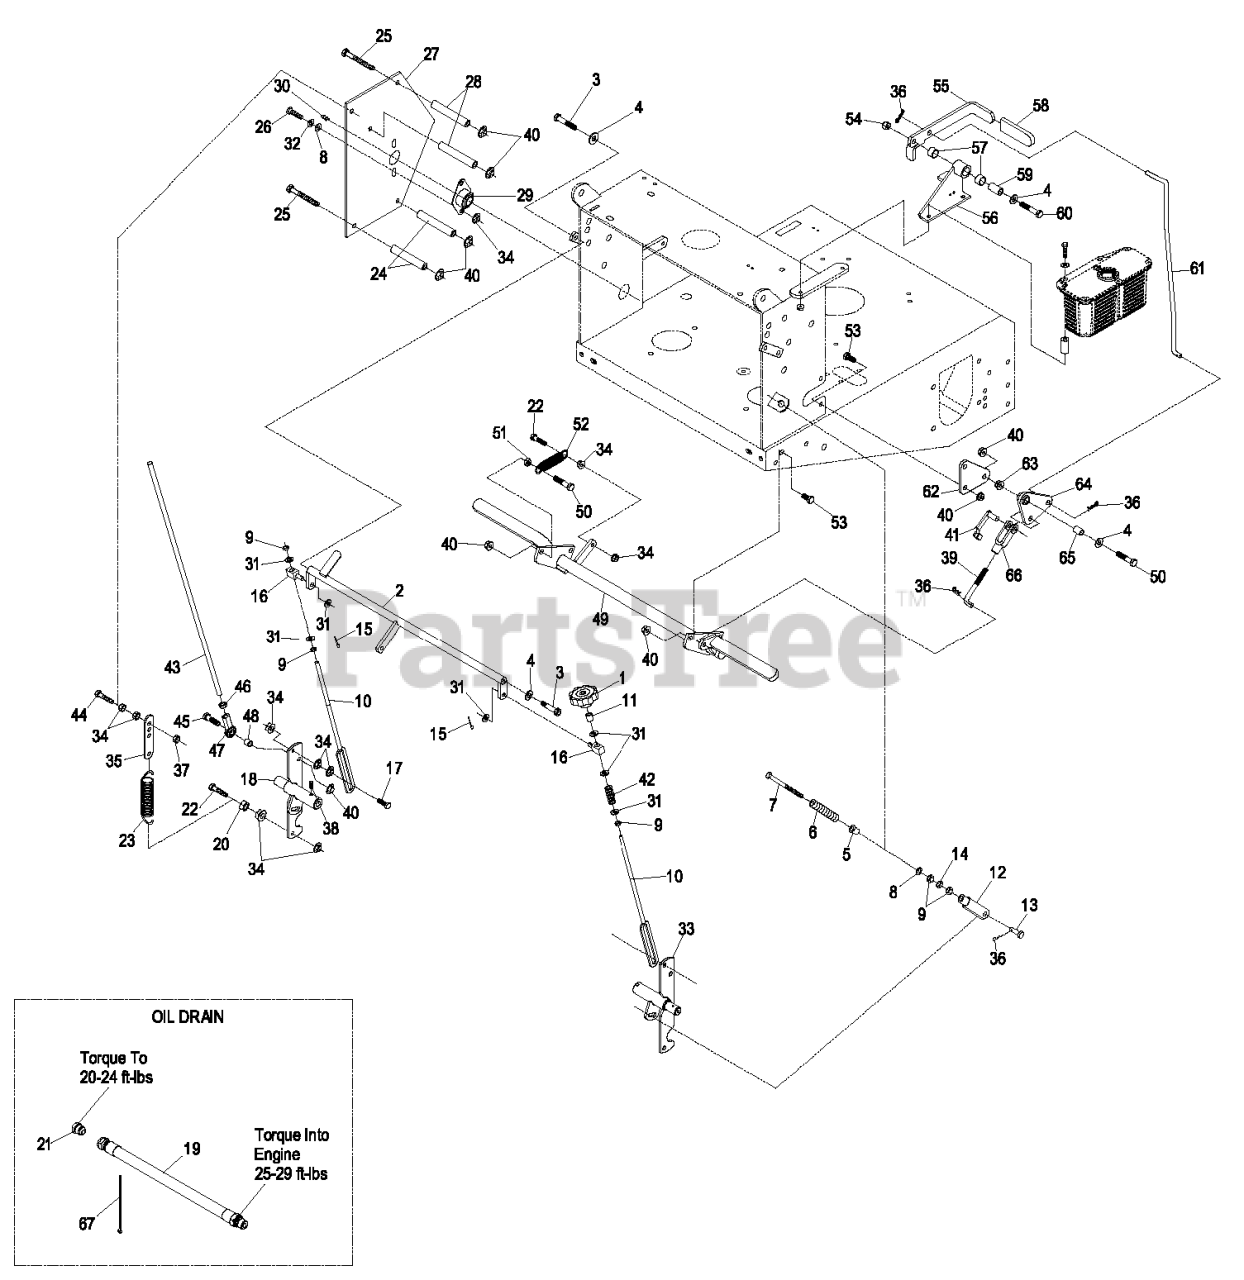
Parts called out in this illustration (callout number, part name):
1	KNOB-TRACKING
2	CRANK-CONTROL, SPEED
3	SCREW-HSH
4	WASHER-FLAT
5	BUSHING-FLANGED
6	SPRING,COMPRESSION (NEUT)
7	BOLT-RETURN, NEUTRAL
8	WASHER-FLAT
9	NUT-HEX
10	LINK-CONTROL, SPEED
12	YOKE-ADJUSTABLE
13	PIN-CLEVIS
14	NUT-JAM
15	PIN-COTTER
17	SCREW-HH
18	SHAFT-CONTROL, LH
20	NUT-JAM
22	SCREW-HH
23	SPRING-EXTENSION
24	SPACER-SHIELD
25	SCREW-HH
26	SCREW-HH
27	SHIELD-CONTROL
28	SPACER-SHIELD
29	BEARING-FLANGE, SIDE
30	FITTING-GREASE
31	WASHER-PLAIN
32	WASHER-LOCK
33	SHAFT-CONTROL, RH
35	TAB-SPRING, EXTENSION
36	PIN-COTTER
37	NUT-LOCK, NI
38	SCREW-SET
39	LINKAGE-LOWER
40	NUT-HHF, WHIZ
41	PIN-SPRING, CLEVIS
42	SPRING-COMPRESSION
43	LINKAGE,DRIVE (PLT)
44	BOLT-TAP, HH
45	SCREW-HH
46	NUT-HEX JAM, LH
47	JOINT-BALL END, LH
48	SPACER-TUBE, PUMP LINK
50	SCREW-HH
51	NUT-JAM
52	SPRING-IDLER
53	SCREW-HH
54	NUT-LOCK, NI
55	LEVER,PARK BRK W/DECAL
56	BRACKET ASM
57	SLEEVE-BUSHING
58	GRIP-LEVER
59	BUSHING-PIVOT
60	SCREW-HH
61	LINKAGE-UPPER
62	BELLCRANK
64	BELLCRANK ASM
65	BUSHING-PLASTIC
66	YOKE-LINKAGE, BRAKE
67	TIE-CABLE
